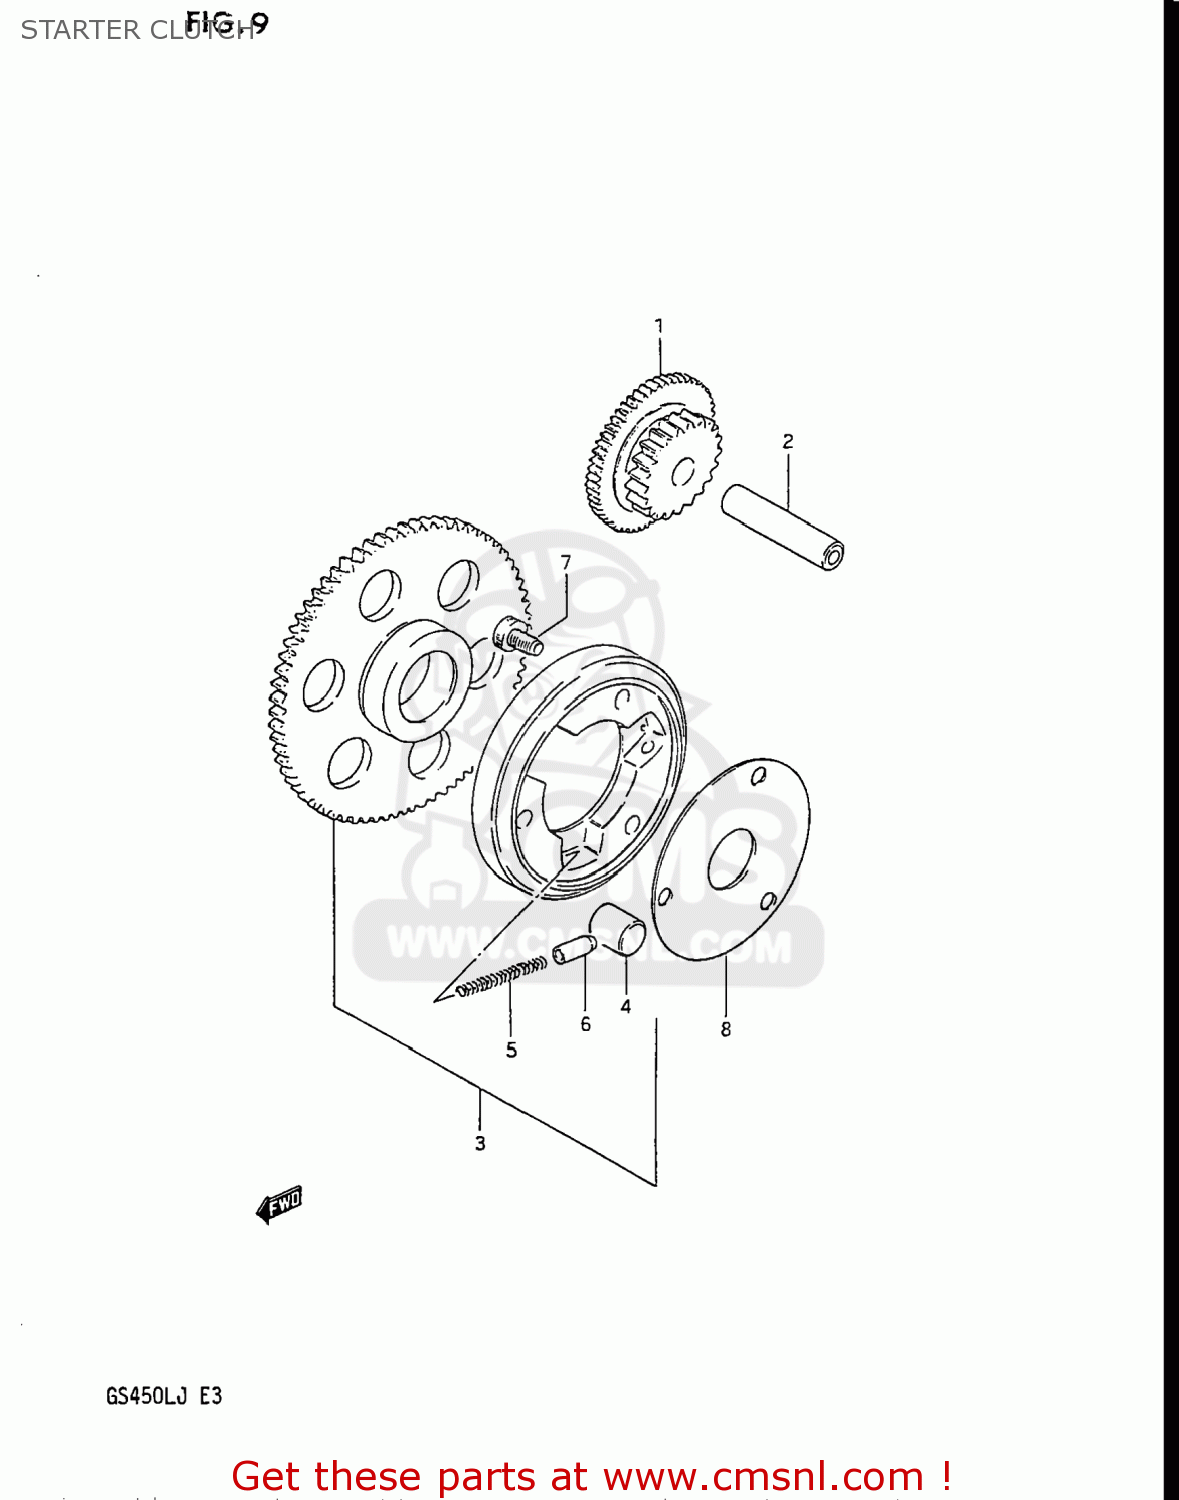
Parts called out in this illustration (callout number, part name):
1	GEAR,STARTER IDLE
2	PIN(7.4X13X56)
3	CLUTCH SET,STARTER
4	ROLLER(15X13)
5	SPRING
6	PIECE,PUSH
7	BOLT
8	SHIM,STARTER CLUTCH HUB
